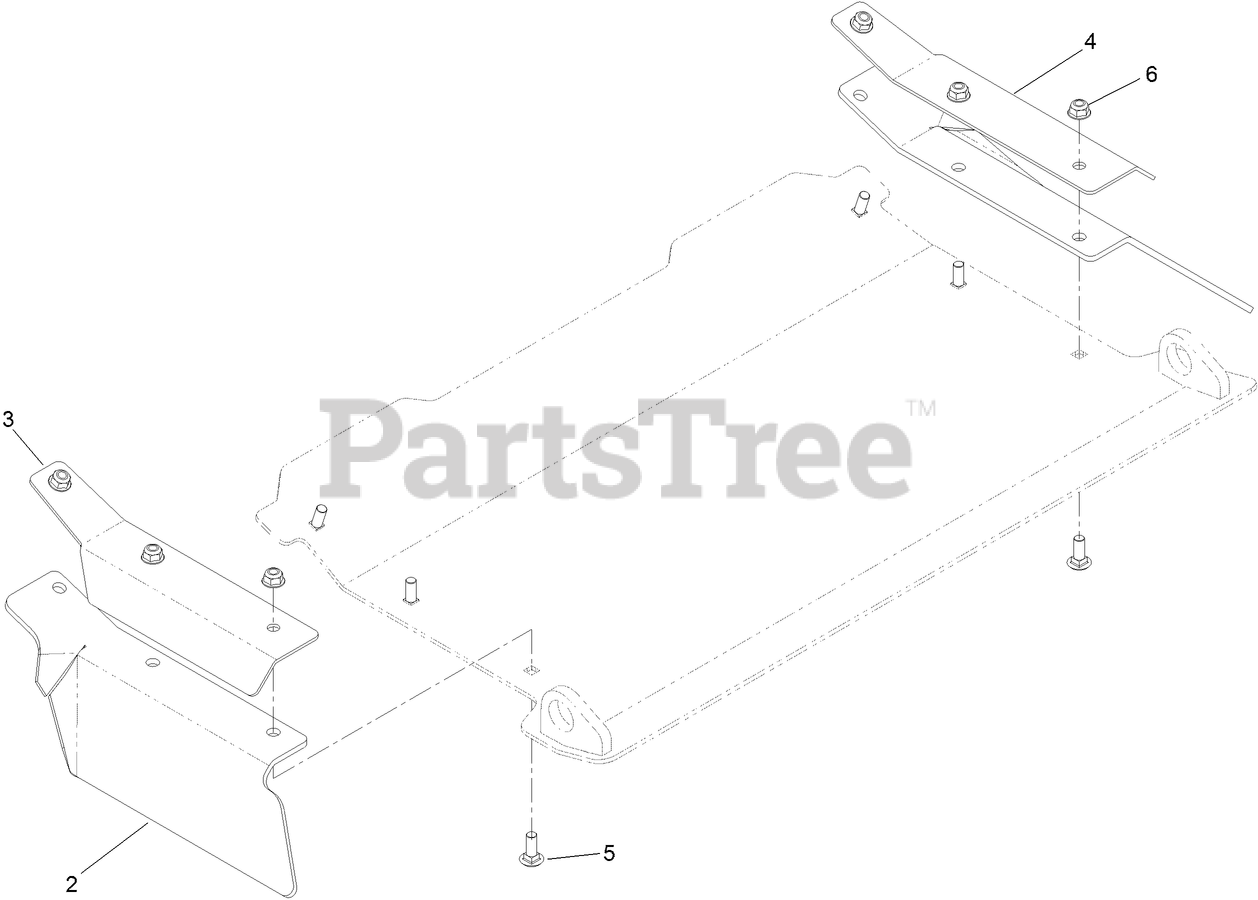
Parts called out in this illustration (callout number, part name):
2	FLAP-RUBBER
3	BRACKET-FLAP, LH
4	BRACKET-FLAP, RH
5	SCREW-CARR
6	NUT-HF, NI
